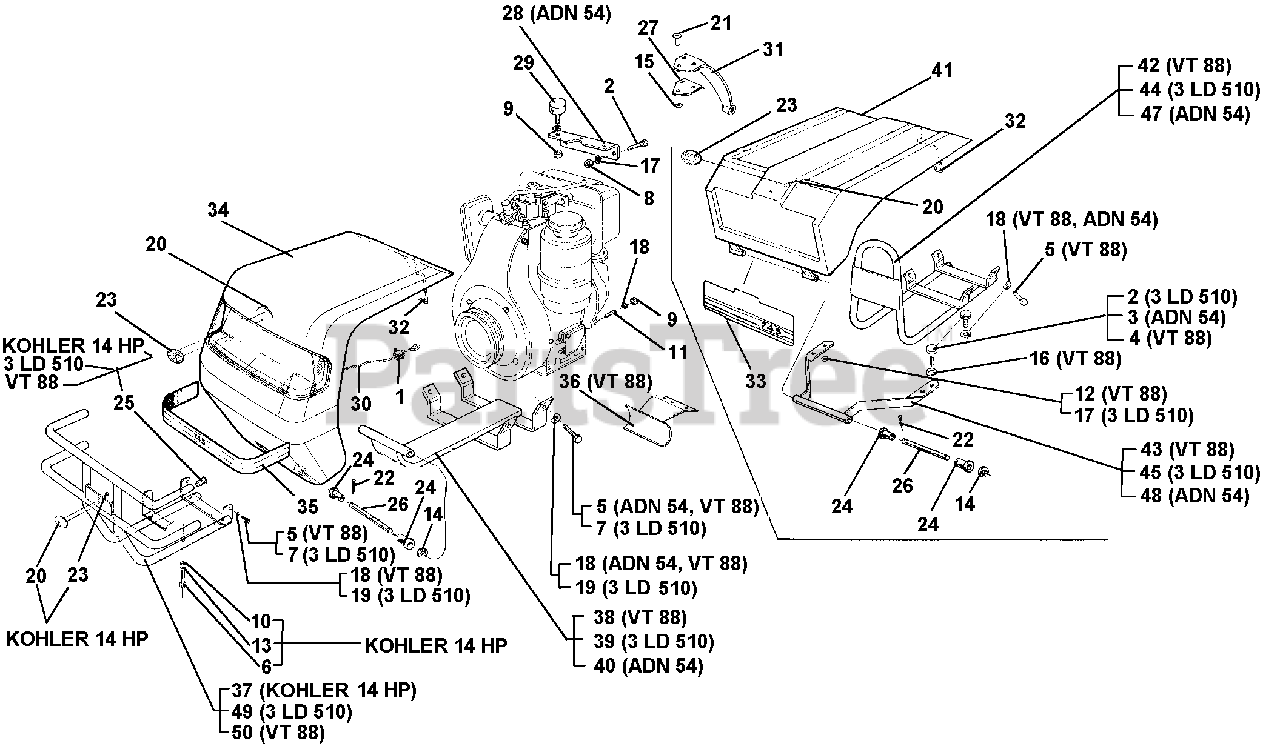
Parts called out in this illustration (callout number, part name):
1	CLAMP, CABLE 3/16
2	SCREW TE M6 X 14
3	SCREW M8 X 16
5	SCREW M8 X 20
6	SCREW M8 X 60
7	SCREW TE M10 X 20 UNI 5739-8G
10	NUT, SELF LOCKING M8
11	STUD M8 X 40 X 14 X 14
12	WASHER, FLAT 6.4
13	WASHER, FLAT 8.4
14	FLAT WASHER 10.5 X 21
16	SUPER WASHER 6 DIN 6796
17	WASHER, LOCK 6.4
18	WASHER, LOCK 8.4
19	WASHER, LOCK 10.5
20	WASHER, LOCK FOR PINS D-4
22	PIN, COTTER A 3 X 20 UNI 1336
26	PIN, COUPLING
28	TANK COUPLING
30	COVER CABLE
33	TRANSFER 745E
34	ENGINE COVER
35	AUTOADHESIVE STRIP
36	TANK COUPLING
37	BUMPER FOR KOHLER ENGINE
38	LOWER COUPLING
39	LOWER COUPLING
40	LOWER COUPLING
41	COVER FOR 745
42	PULLEY GUARD
43	FRONT COUPLING
44	PULLEY GUARD
46	FRONT COUPLING 3LD 510
47	PULLEY GUARD
48	FRONT COUPLING
49	BUMPER FOR ENGINE 3LD 510
50	BUMPER VT/88
